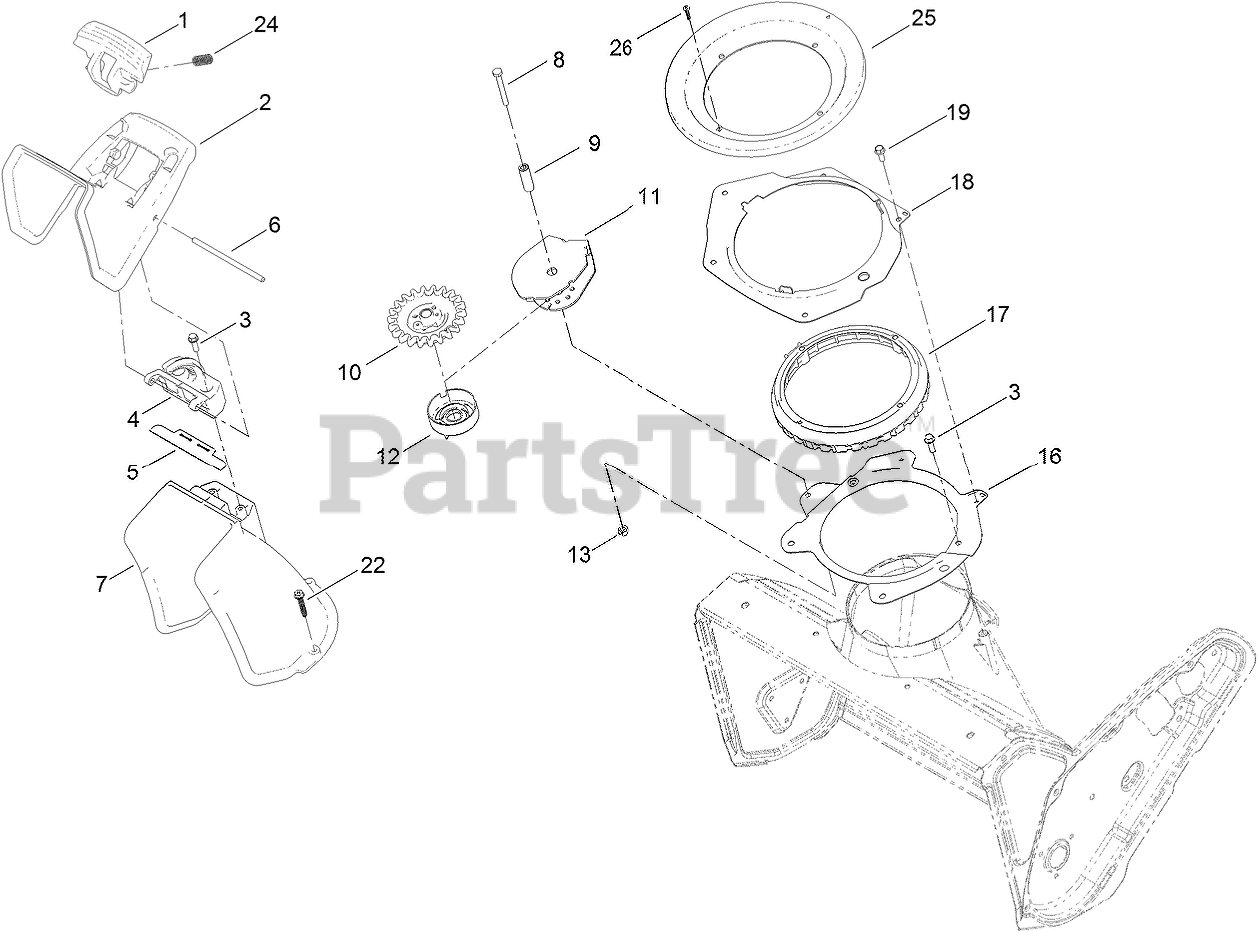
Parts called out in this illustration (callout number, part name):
1	TRIGGER-DEFLECTOR
2	DEFLECTOR-CHUTE, CE
3	SCREW-HWH
4	HINGE-RATCHET, DEFLECTOR
5	SEAL-DEFLECTOR
6	PIN-HINGE, DEFLECTOR
8	SCREW-HH
9	SPACER-SLEEVE, PINION
10	PINION-GEAR
11	BRACKET-PINION
12	RETAINER-CABLE
13	NUT-LOCK, NI
16	RING-SUPPORT, CHUTE
17	RING-CHUTE, GEAR
18	RETAINER-RING, CHUTE
19	SCREW-HWH
22	SCREW-PLASTITE
24	SPRING-COMPRESSION
25	SEAL-RING, CHUTE
26	SCREW-PPH
